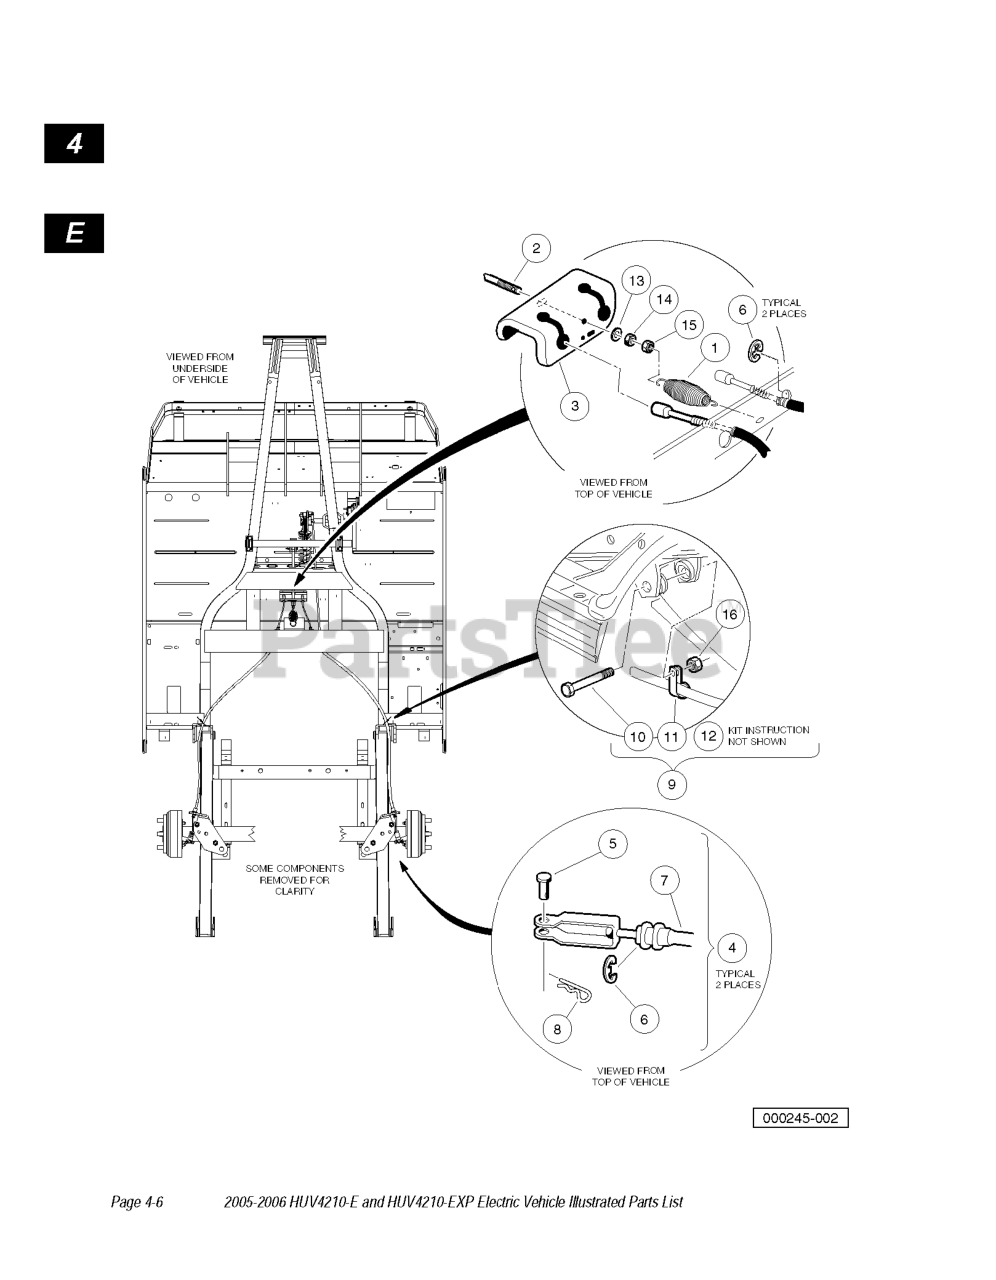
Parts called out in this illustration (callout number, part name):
1	SPRING, BRAKE RETURN
2	ROD, EQUALIZER, 8.91"
3	EQUALIZER BRACKET
4	BRAKE CABLE KIT
6	E-CLIP, 1/2
8	PIN,CUT COTTER
9	KIT, FIELD P-CLAMP, BRAKE LINE
10	SCREW, 3/8-16 X 3.50 HEX CAP
11	P-CLAMP, BRAKE LINE
12	Instr Fd. P-clamp, Brake Line
13	WASHER, 5/16 TYPE A FLAT
14	NUT, 5/16-18 HEX
15	LOCKNUT, 5/16-18 NYLON INSERT
16	LOCKNUT, 3/8-16 HEX
